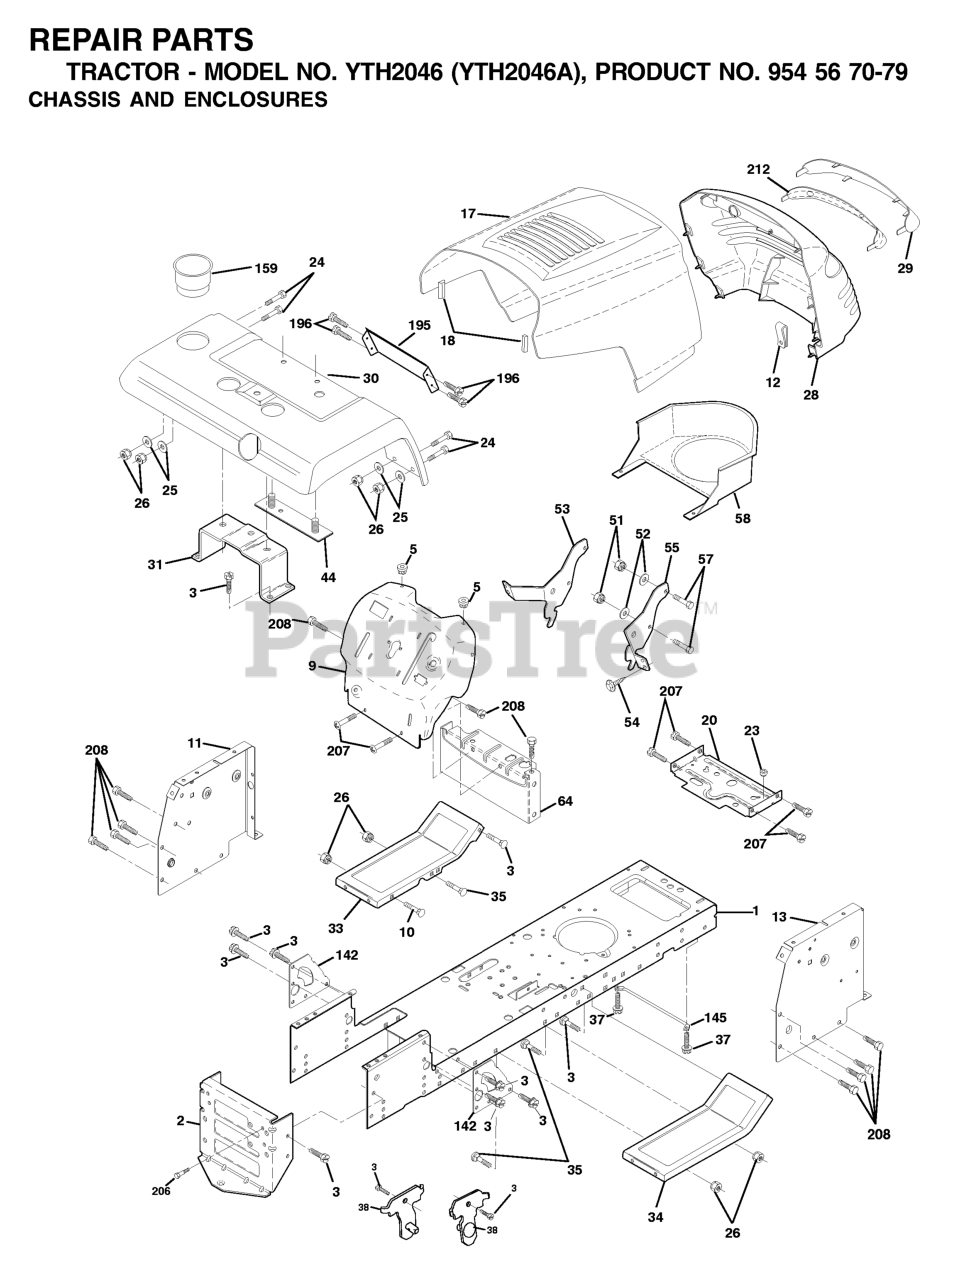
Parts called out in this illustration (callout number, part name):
2	DRAWBAR
3	SCREW 3/8-16X3/4
5	BUMPER.RUBBER.HOOD
9	DASH SLKSCR
10	BOLT D
11	PANEL DASH LH
13	PANEL ASM, DASH RH
17	HOOD ASM.
18	BUMPER HOOD T
20	PLATE MTG
23	BUSHING.SNAP.NYL.BLK.
25	WASHER
26	NUT
28	GRILLE ASM
29	LENS
31	BRACKET ASM, FENDER
33	FOOT REST LH
34	FOOTREST RH
37	Screw 5/16-18 x 1/2 Hex, Self Tapping 5/16-18 x 1/2
38	BRACKET
44	STRAP
51	LOCKNUT.NYLOC.1/4-20
53	BRACKET.GRILLE.LH
54	SCREW.HEX.WS.HD.8-18 X 7/8
57	BOLT
58	DUCT, INTAKE AIR
64	DASH LOWER
142	PLATE
145	ROD PIVOT CHASSIS/HOOD
196	SCREW CRT
206	SHOULDER BOLT 5/16-18TT
207	SCREW, 5/16-18 X 1/2
208	SCREW 3/8-16X1/2
212	REPL BY 532 1745-03
